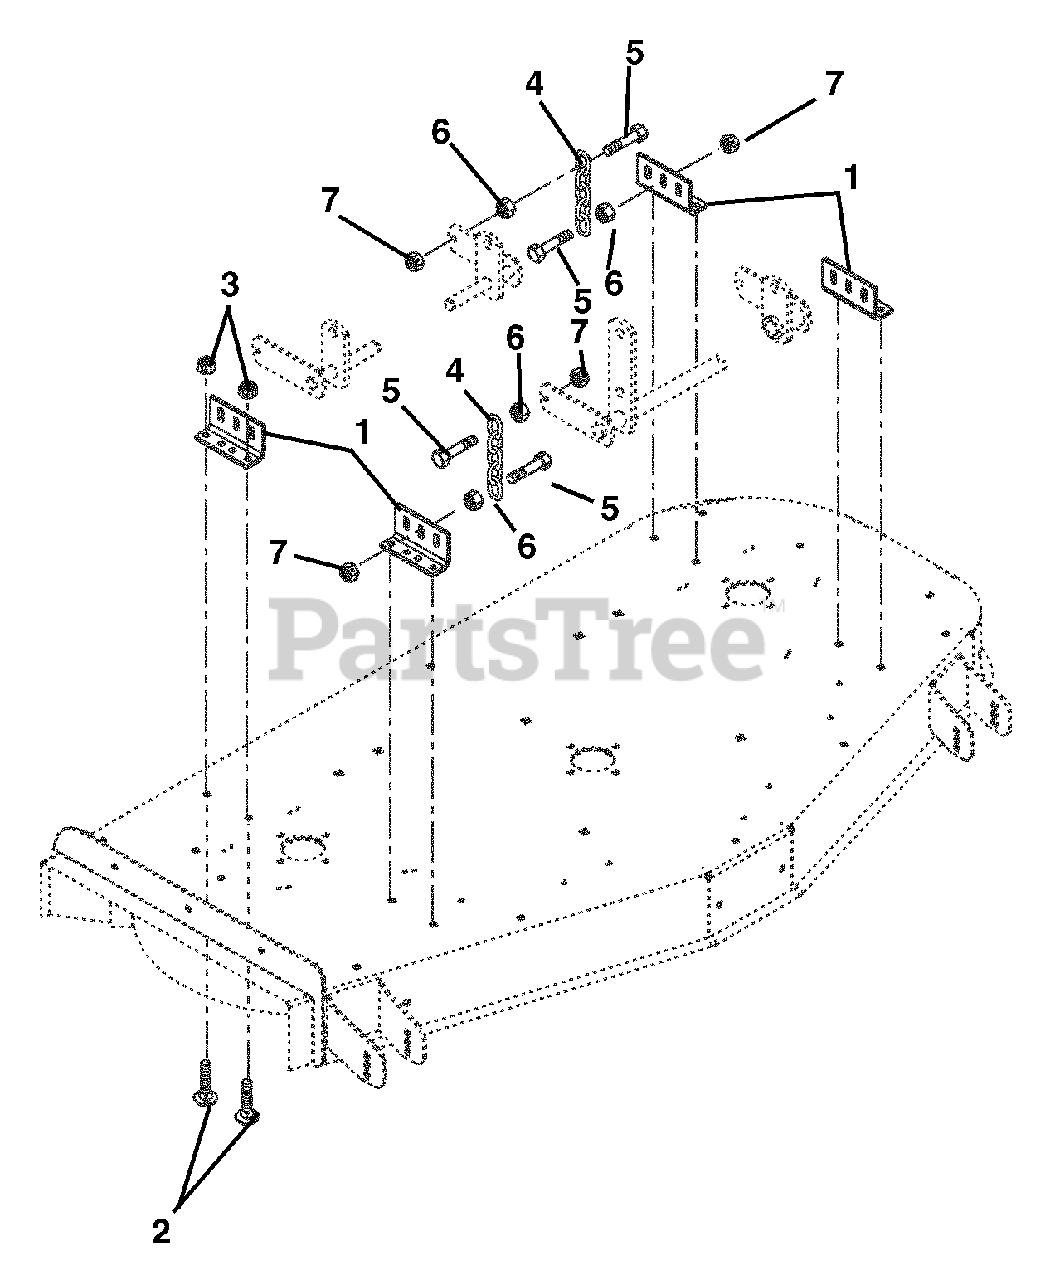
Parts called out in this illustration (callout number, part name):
1	Bracket, Mower Mounting
2	Bolt-Round Head Square Neck .38-16 x 1.00 Grade 5 (036, 038, 309)
3	Nut-Locking-Top-Flange .38-16
4	Chain, Link
5	Bolt-Hex .50-13 x 2.00 Grade 5
6	Nut-Spin Lock-Flange 0.5-13
7	Nut-Locking-Top-Flange 0.50-13
